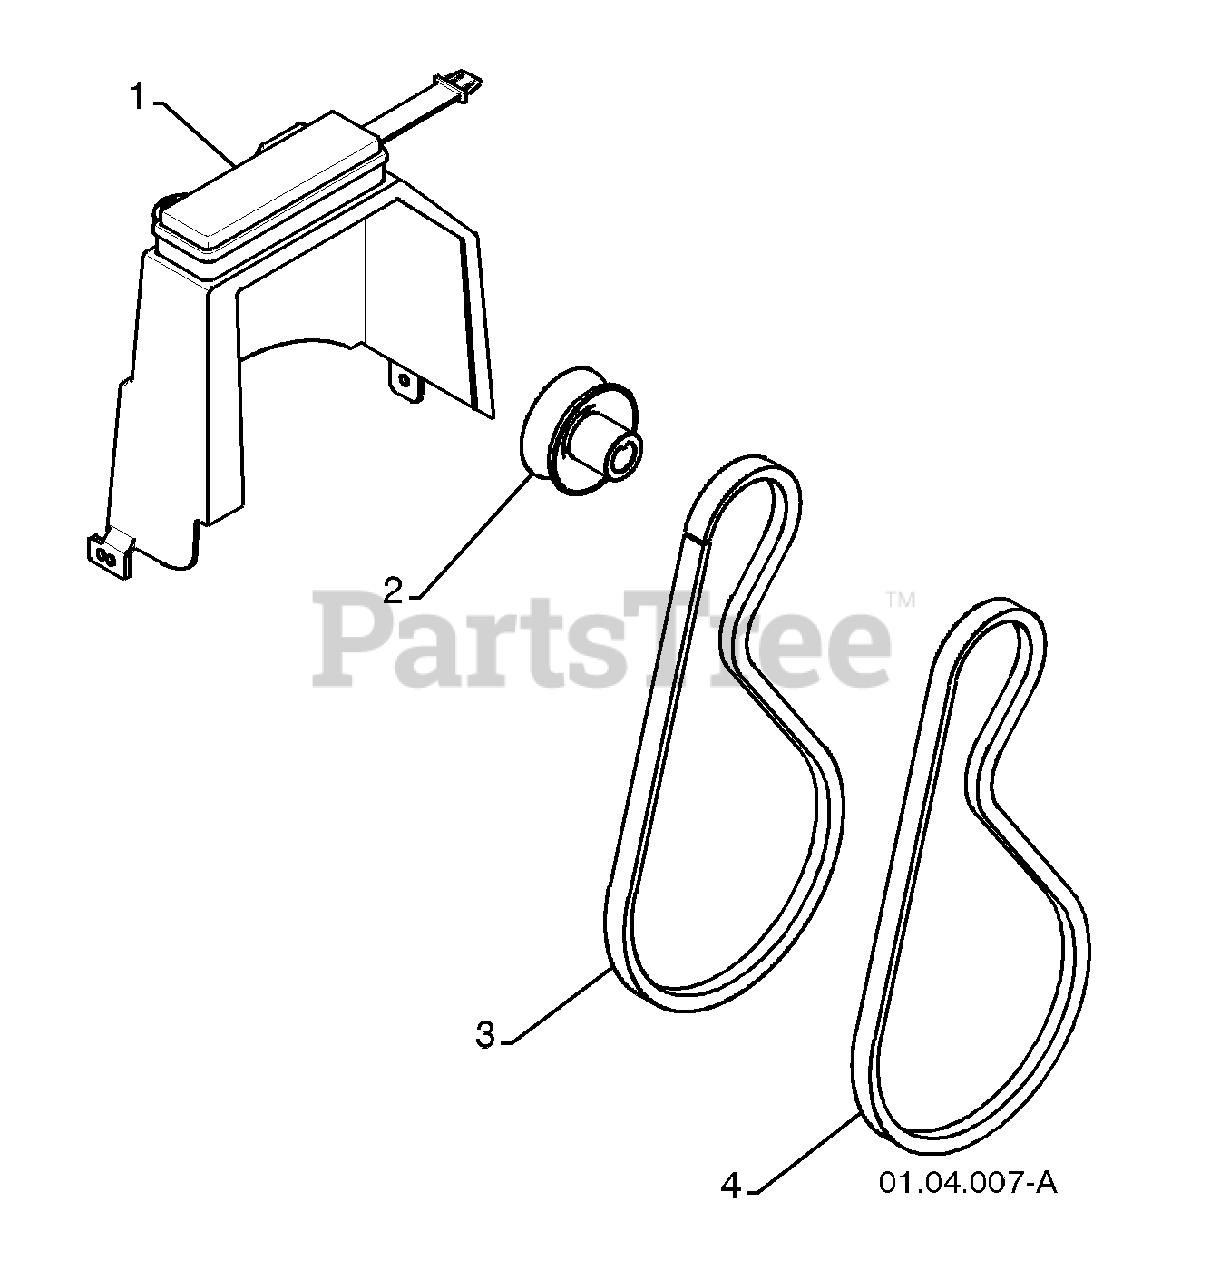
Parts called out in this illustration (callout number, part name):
1	COVER ASSEMBLY
2	PULLEY
3	TRACTION BELT
4	IMPELLER BELT
